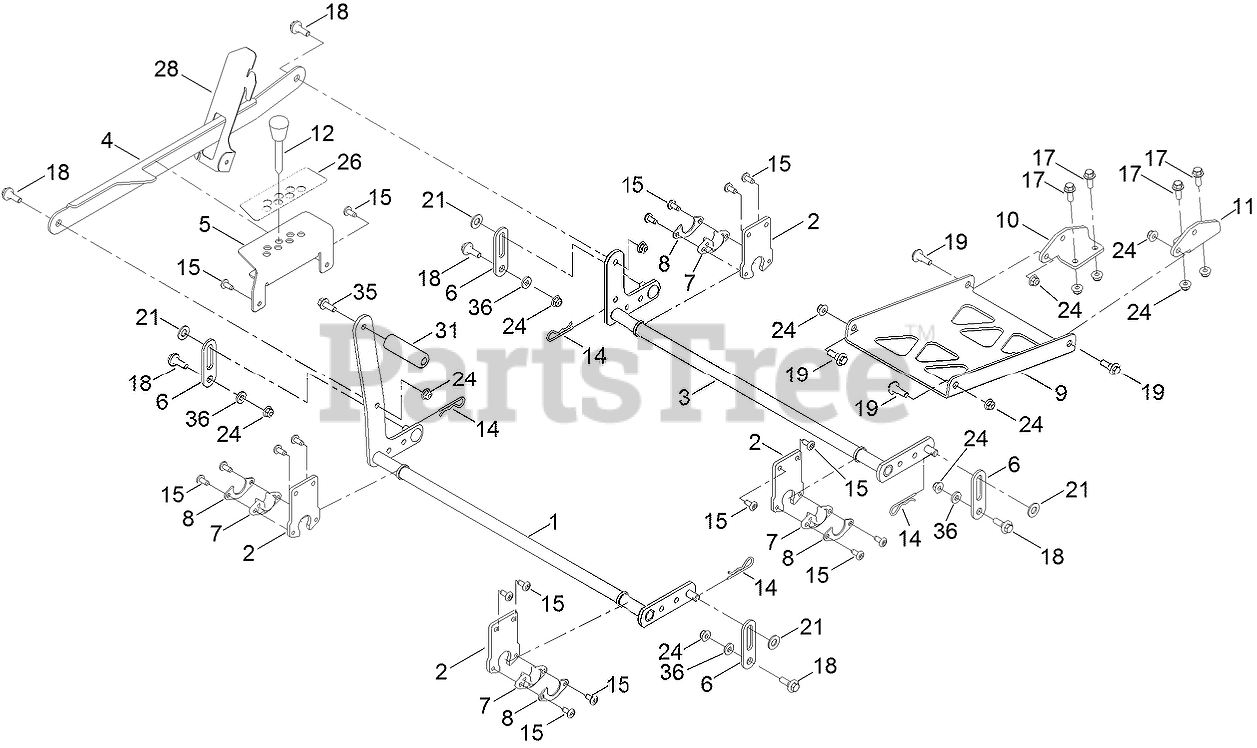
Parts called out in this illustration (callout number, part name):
1	PIVOT FRONT ASM
2	SUPPORT-CROSS, SHAFT
3	REAR PIVOT ASM
4	LINK-HOC
5	BRACKET-HOC
6	LINK-DECKLIFT
7	BEARING-FLANGE
8	GUSSET-DECK LIFT
9	PAN-DECK PIVOT
10	MOUNT-PAN, LH
11	MOUNT-PAN, RH
12	HOC PIN ASM
14	PIN-COTTER
17	SCREW-HHF
18	SCREW-SHOULDER
19	SCREW-SHOULDER, HHF
21	WASHER-FLAT
24	NUT-HF, NI
26	DECAL-HOC
28	BRACKET-HOC
31	PEDAL-FOOT LIFT
35	SCREW-HHF
36	SPACER
